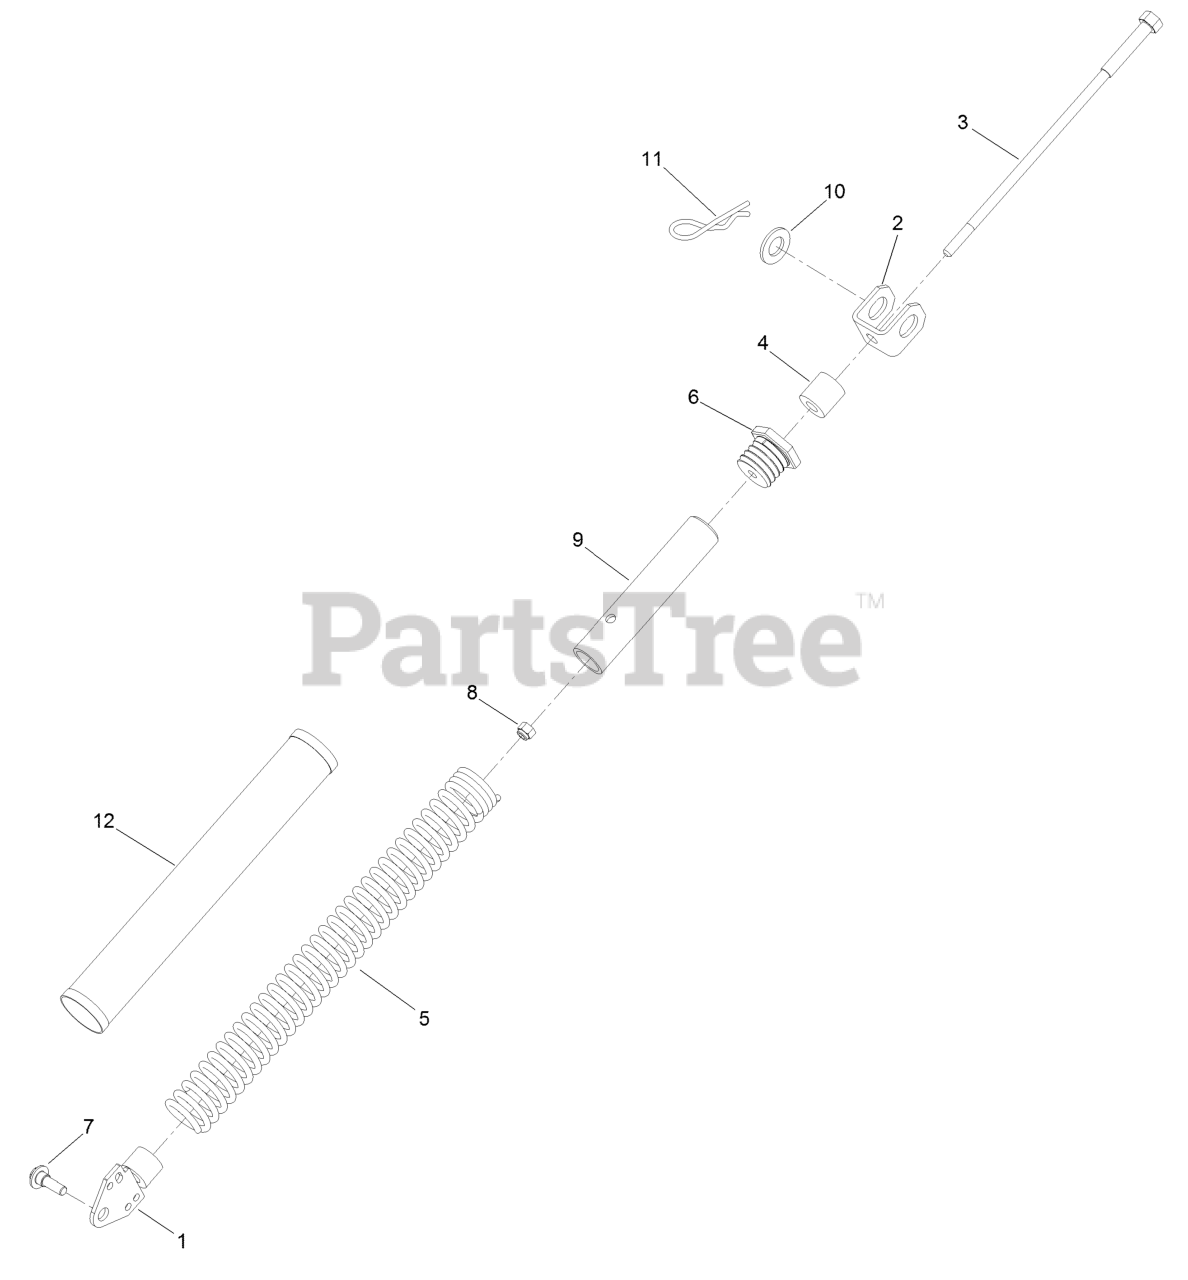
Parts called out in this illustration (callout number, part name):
1	TENSIONER-SPRING
2	MOUNT-LIFT ASSIST, DECK
3	SHAFT-ADJUSTMENT, SPRING
4	SPACER (PLATED)
5	SPRING-EXTENSION
6	PLUG-ADJUSTER, SPRING
7	SCREW-SHOULDER, HWH
8	NUT-LOCK, NI
9	SPRING-TUBE
10	WASHER-FLAT
11	PIN-CUT HEIGHT
12	COVER-SPRING, DECK
